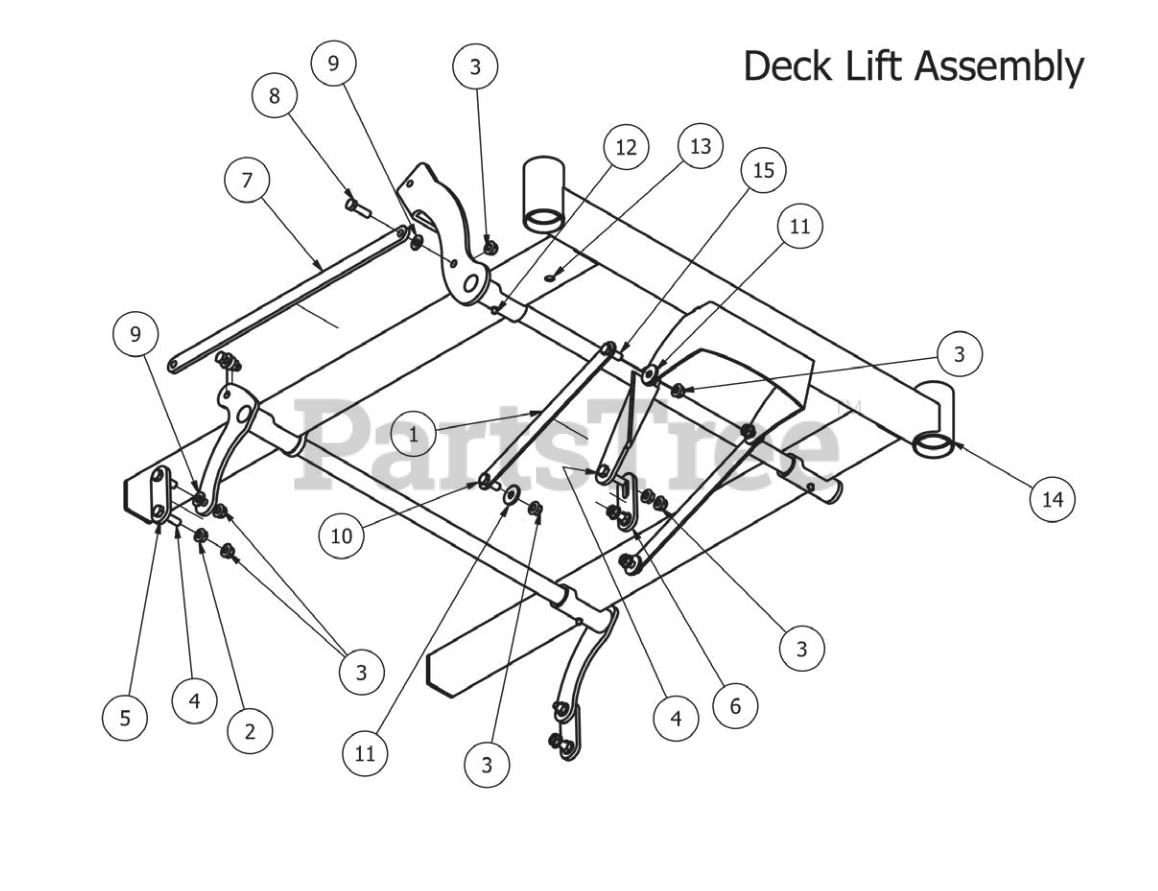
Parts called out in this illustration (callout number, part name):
1	MZ Front Arms
2	3/8" Flange Nut
3	3/8" Nylock Flange Nut
4	3/8" x 1 1/2" Hex Bolt
5	Deck Spacer (Rear)
6	Deck Spacer (Front)
7	Deck Linkage Rod
8	3/8" x 1 1/4" Hex Bolt
9	.360 ID Plastic Washer
10	3/8" x 1" Hex Bolt
11	.390 ID Plastic Washer
12	1/4" Drive in Grease Fitting
13	5/8 Round insert
14	Wheel bearing Container
15	3/8-16 x 1-1/4 GR 5 Hex Bolt
